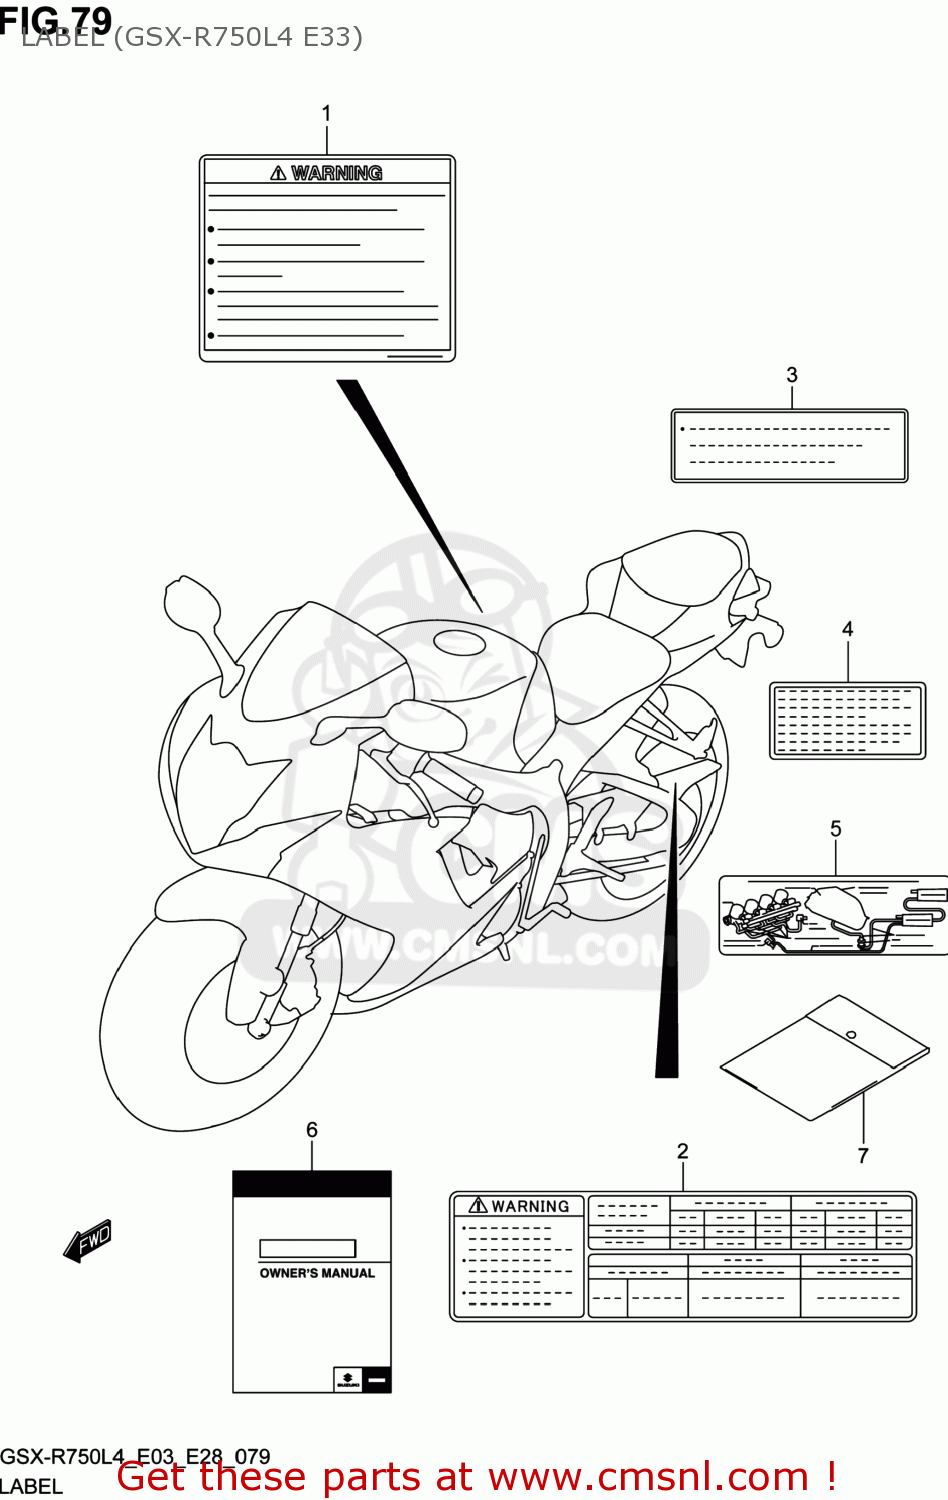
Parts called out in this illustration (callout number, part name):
1	LABEL,GENERAL WARNING
2	LABEL,TIRE INFORMATION
3	LABEL,FUEL INFORMATION
4	LABEL,MANUAL NOTICE
5	LABEL,VACUUM HOSE ROUTING
6	MANUAL,OWNER'S
7	BAG,OWNER'S MANUAL
